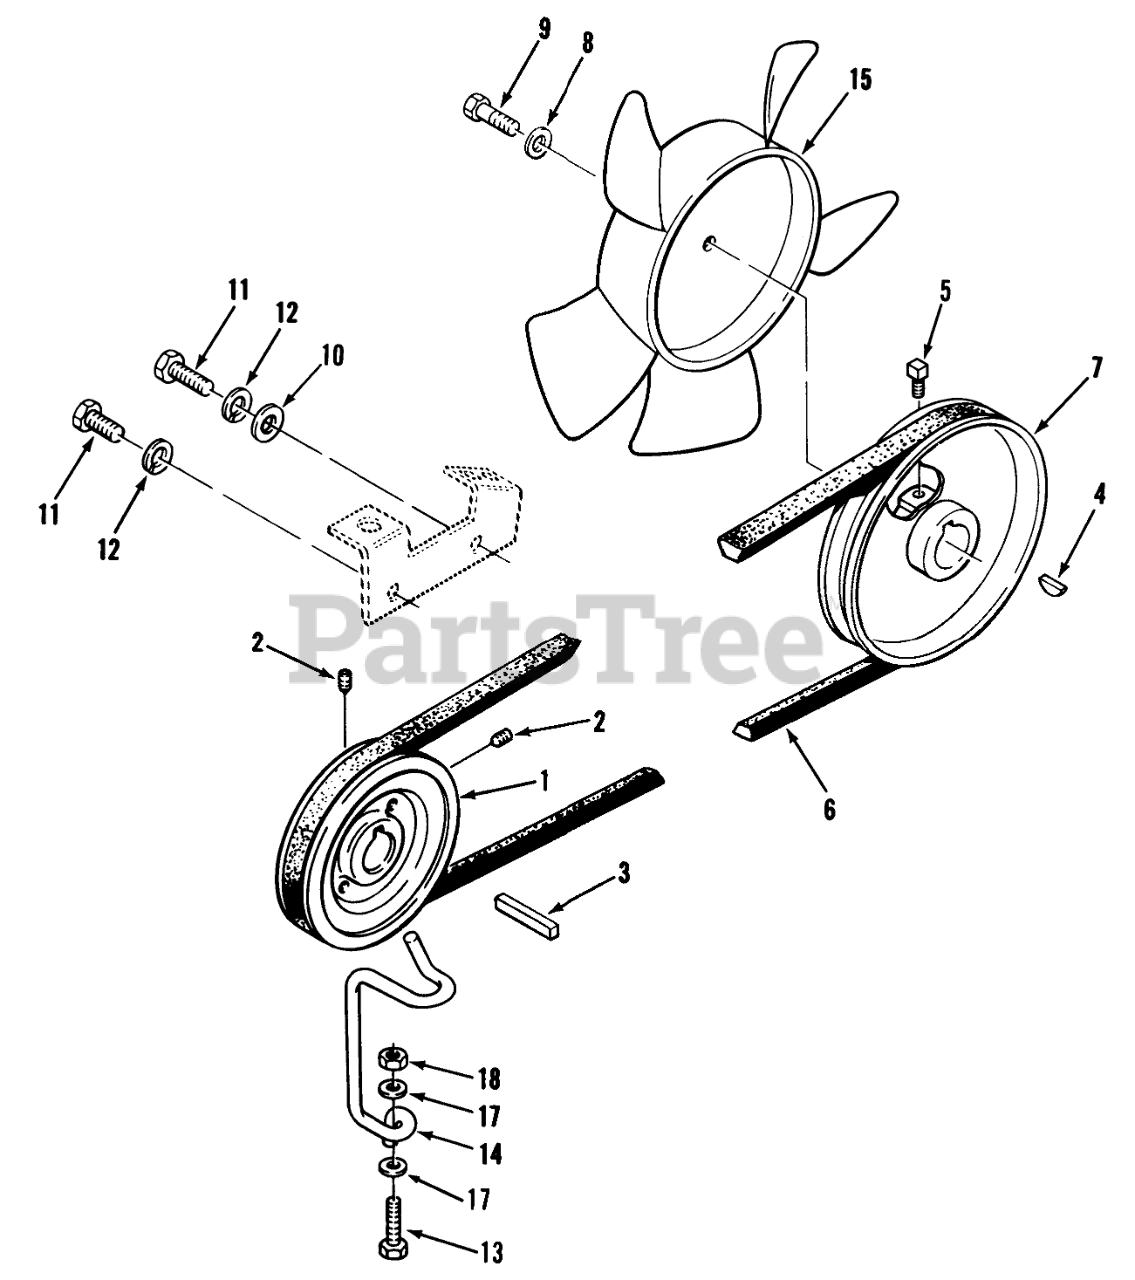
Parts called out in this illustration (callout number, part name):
1	PULLEY
2	Set Screw
4	KEY-HI PRO
5	Set Screw
6	BELT-V
7	PULLEY
8	WASHER
9	H H C S
10	WASHER
11	7/16-14 x 1 1/4 Bolt
12	LOCKWASHER
13	Bolt 5/16-18 x 1-1/4
14	GUIDE-BELT BOTTOM
15	NYLON FAN-L-CW
17	Collar
18	Nut
